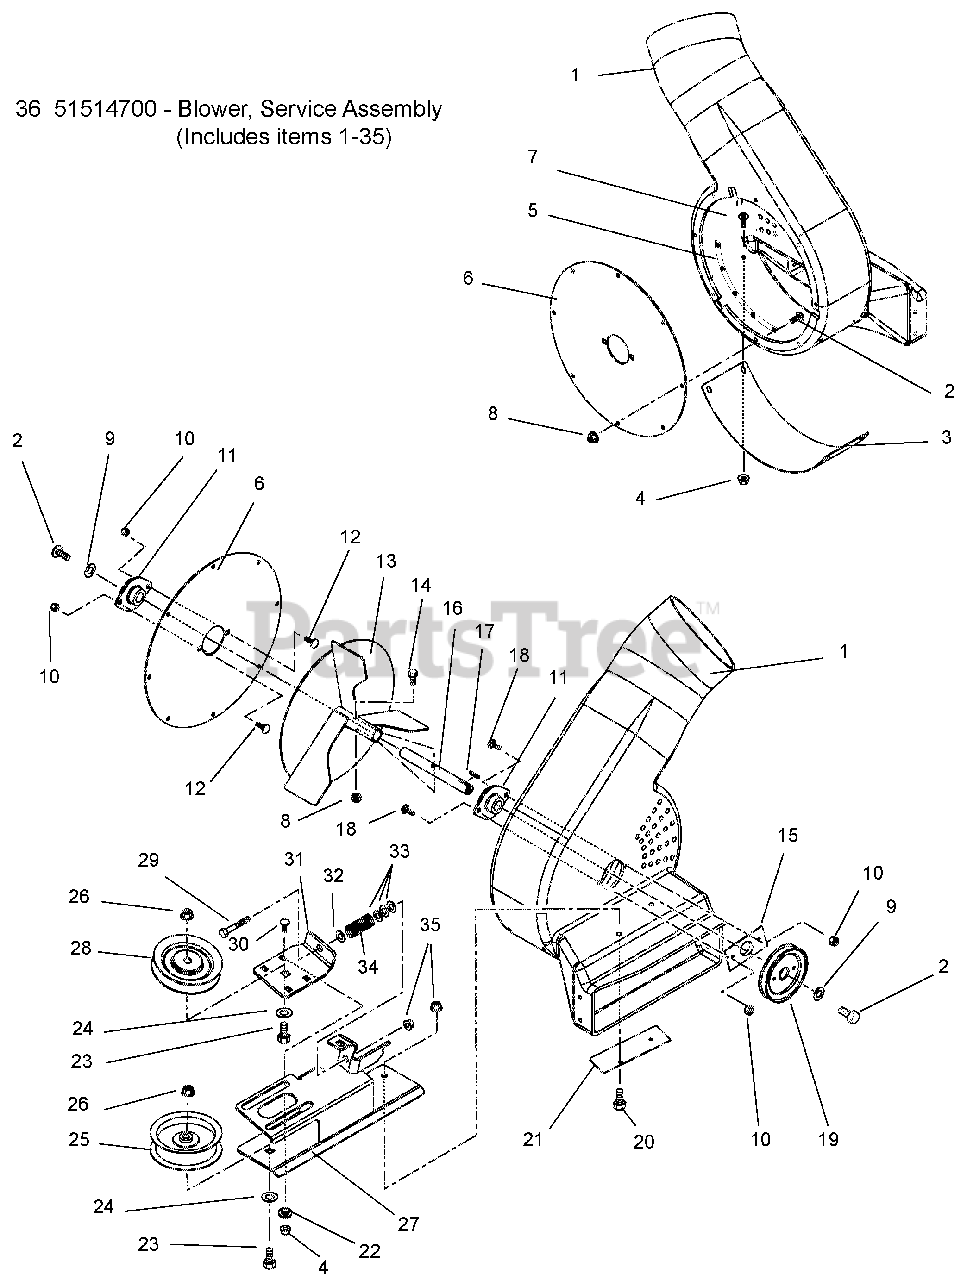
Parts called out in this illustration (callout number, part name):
1	Housing, Blower
2	Bolt, Hex .25-20 x .50 Epoxy
3	Plate, Skid
4	Nut, Locking-Top-Flange .25-20
5	Plate, Mounting Bolt Reinforcing
6	Plate, Bearing Mount
7	Screw, Machine .25-20 x .75
8	Nut, .25-20 Nyloc Flange
9	Washer, Flat-Steel .344 x 1.125 x .135
10	Nut, Locking-Nylon .312-18
11	Bearing, 2 Bolt Flange - .75 ID
12	Bolt, Round Head Square Neck .31-18 x .62
13	Weldment, Impeller, 3 Blade
14	Bolt, Hex .25-20 x 1.50 Grade 5
15	Plate, Washer Bearing
16	Shaft, Impeller
17	Key, Square .187 x .50 x .187 Hardened
18	Bolt, Round Head Square Neck .31-18 x .88 Grade 5
19	Sheave, Blower 4.25 Diameter
20	Bolt, Hex .31-18 x .875 Grade 5
21	Plate, Back
22	Bushing, Flange .265 x .437 x .250 x .750
23	Bolt, Hex .38-16 x 1.75 Grade 5
24	Washer, Flat-Steel .406 x .812 x .065
25	Idler Flanged 3.50
26	Nut, Locking-Top-Flange .38-16
27	Weldment, Idler Mount
28	V-Idler, 4.00 x .38
29	Bolt, Hex .31-18 x 4.00 Grade 5
30	Bolt, Round Head Square Neck .25-20 x .75 Grade 5
31	Bracket, Adjustable Idler
32	Nut, Push .312
33	Washer, Flat-Steel .406 x 1.00 x .188
34	Spring, Compression .092 x .77 x 3.13
35	Nut, Locking-Top-Flange .31-18
36	Blower, Service Assembly (includes items 1-35)
